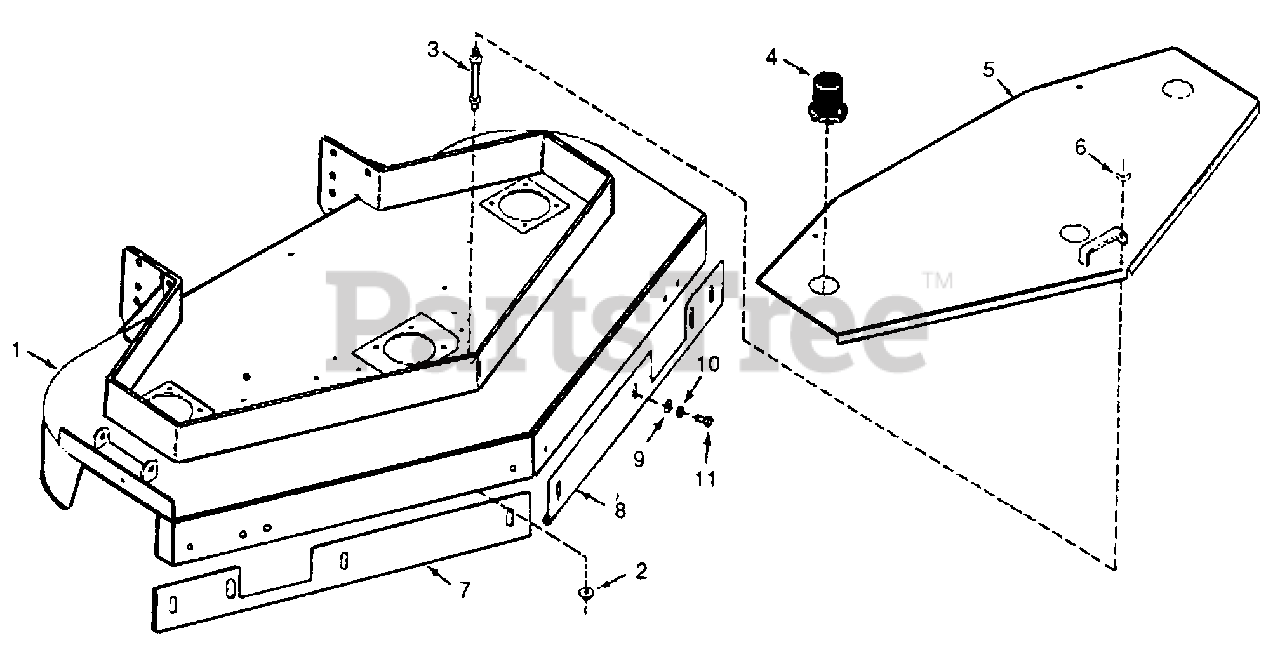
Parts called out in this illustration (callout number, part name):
1	Cuning Deck, 48" W/Decals
2	5/16 -18 Flange Nut
3	Stud, Hood Mount
4	Spindle Guard
5	Belt Cover, 48" W/Decal
6	Wing Nut
7	Front Guard, Right
8	Front Guard, Left
9	3/8" Flat Washer
10	3/8" Loch Washer
11	3/8"-16 x 1' Hex. Hd. Cap Screw
